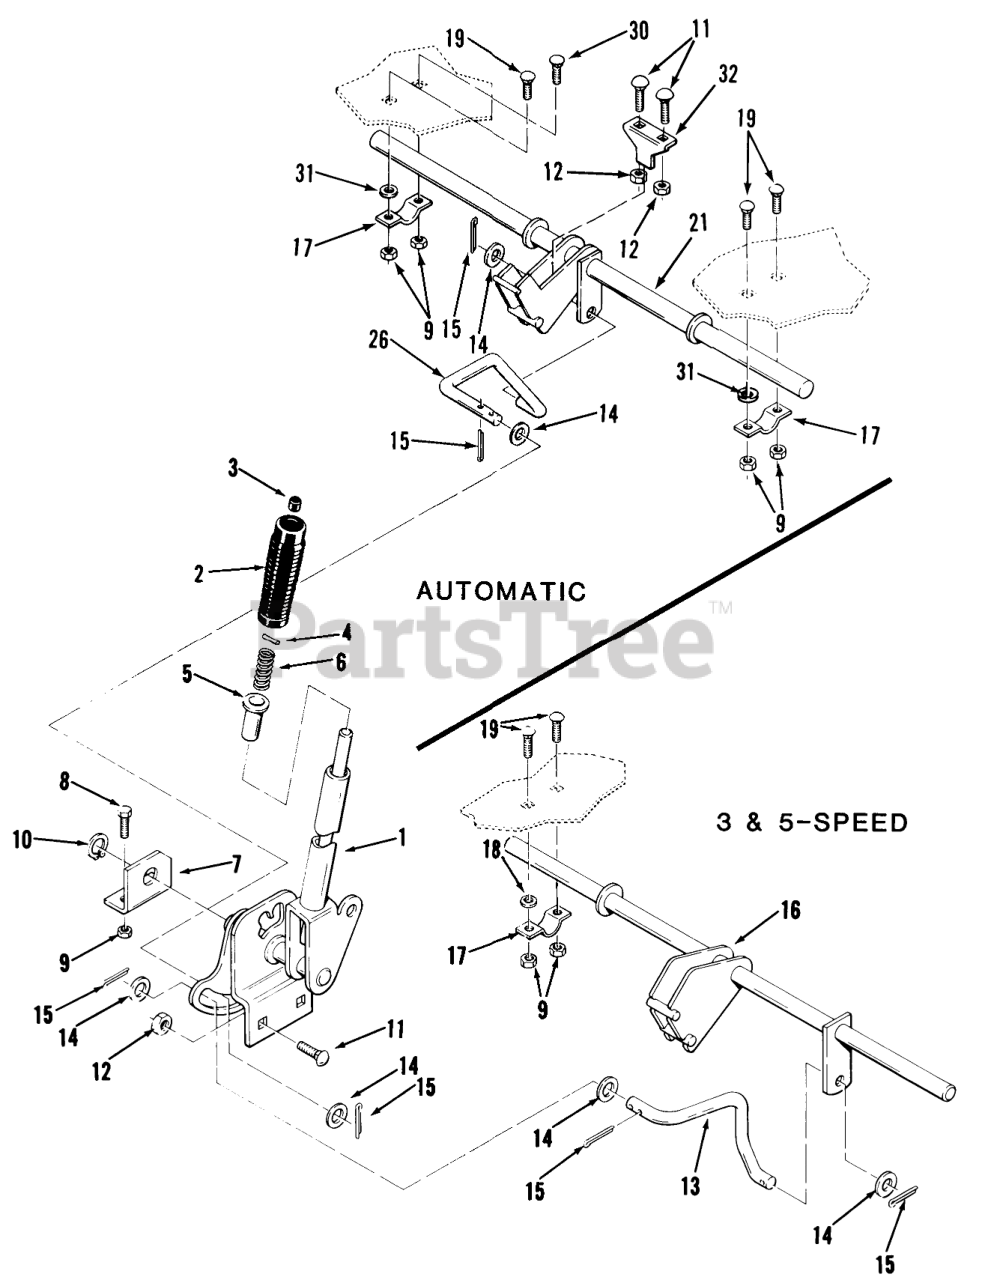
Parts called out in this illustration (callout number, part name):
1	Lift Lever
2	HANDGRIP
3	CAP-ROD, PLUNGER
4	PIN-SPIROL
5	RETAINER-SPRING
6	SPRING-COMPRESSION
7	BRACKET-INNER R
8	Bolt
9	Nut
10	Snap Ring
11	Bolt-Carriage
12	Nut
13	ROD LIFT
14	Washer
16	ASM-REAR LIFT R
17	CLAMP
18	Washer
19	Bolt
21	ASSY REAR LIFT R
26	ROD LIFT R
30	Bolt-Carriage
31	Bolt-Carriage
32	BRACKET STOP
